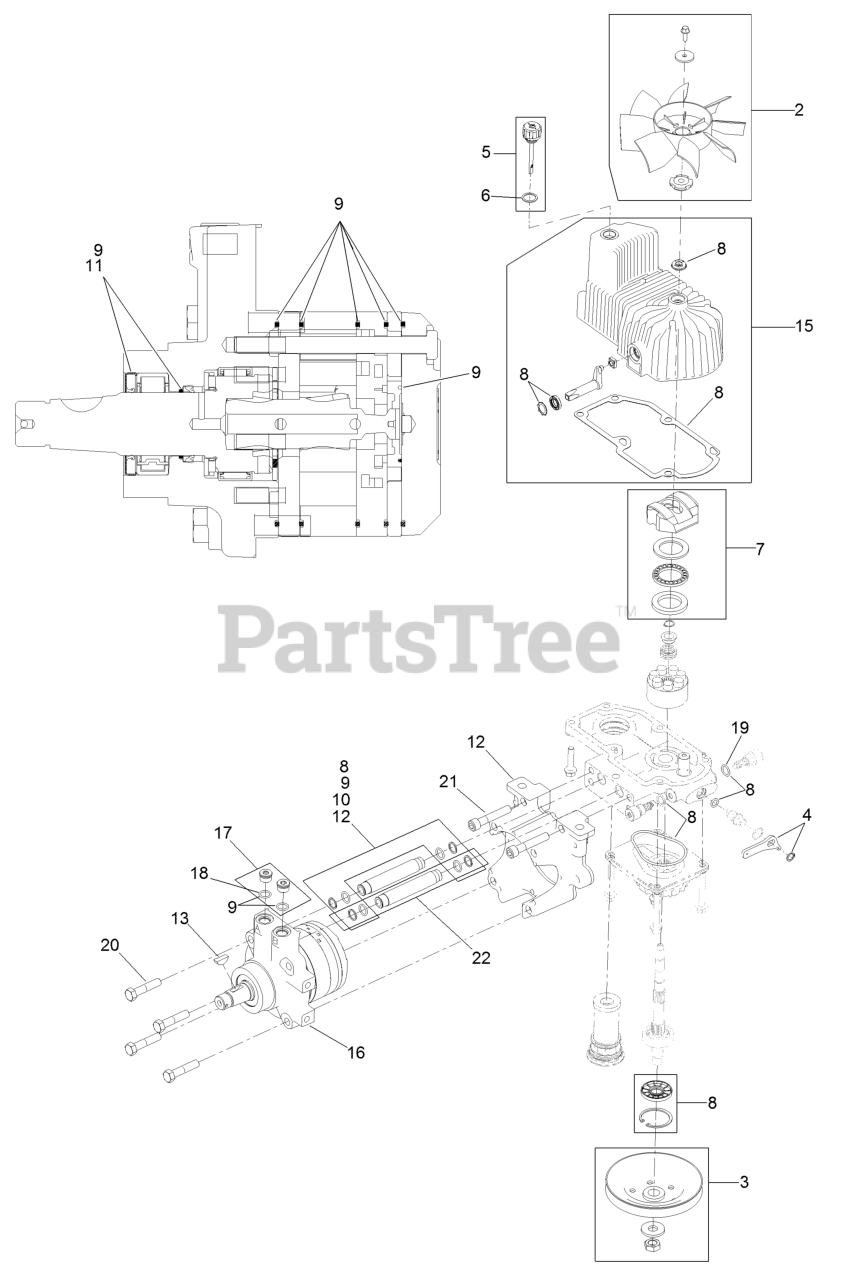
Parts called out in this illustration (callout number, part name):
2	FAN KIT
3	PULLEY KIT
4	HANDLE-BYPASS VALVE, HYDRO
5	DIPSTICK-HYDRO W/GASKET
6	GASKET-DIPSTICK, HYDRO
7	SWASH BLOCK KIT
8	PUMP SEAL KIT
9	MOTOR SEAL KIT
10	TUBE SEAL KIT
11	OUTPUT SHAFT SEAL KIT
12	NOSE CUP-UHT
13	KEY-WOODRUFF
15	HOUSING-HYDRO, LH
16	MOTOR-HYDRAULIC LH 240CC
17	MAGNETIC PLUGS SERVICE KIT
19	O-RING-CHECK VALVE
20	SCREW HH
21	SCREW-HSH
22	HYDRAULIC TUBE KIT
